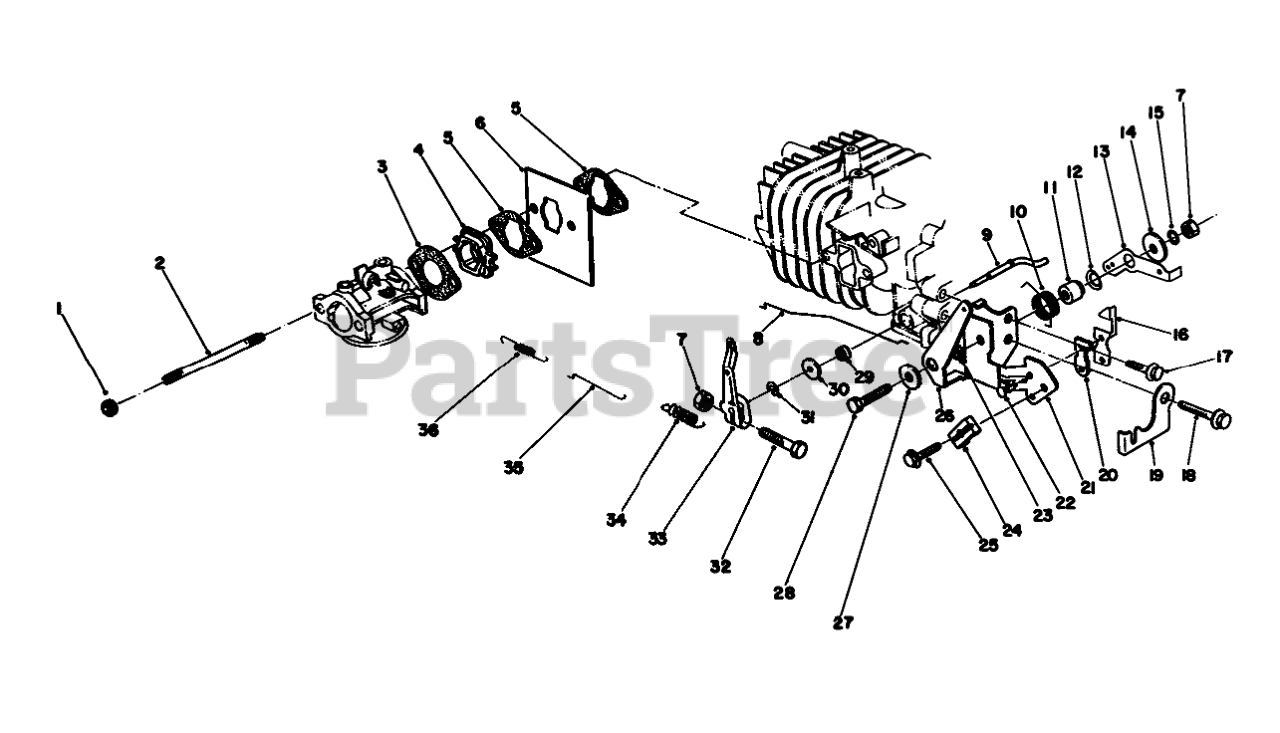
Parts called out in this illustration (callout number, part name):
1	NUT-LOCK
2	CARB STUD BOLT
3	GASKET-CARB
4	INSULATOR
5	GASKET
6	SHIELD
8	CHOKE ROD
9	Shaft-Govemor
10	Spring-Choke Control Lever
11	Gov Lever Spacer
12	Washer-Gov. Spring Lever
13	GOV SPRING LEVER
14	WASHER
15	LOCKWASHER
16	TERMINAL-KILL SWITCH
19	THROTTLE SUPPORT BRKT
20	INSULATOR-KILL SWITCH
21	Bracket-Throttle Control
22	KILL SWITCH RIVET
23	Spacer-Choke Control Lever
24	CLAMP-CABLE
26	LEVER-CONTROL, CHOKE
27	WASHER
29	SEAL-OIL
30	WASHER
31	E-RING
33	Lever-Throttle Control
34	GOVERNOR SPRING
35	ROD-CARBURETOR
36	SPRING
